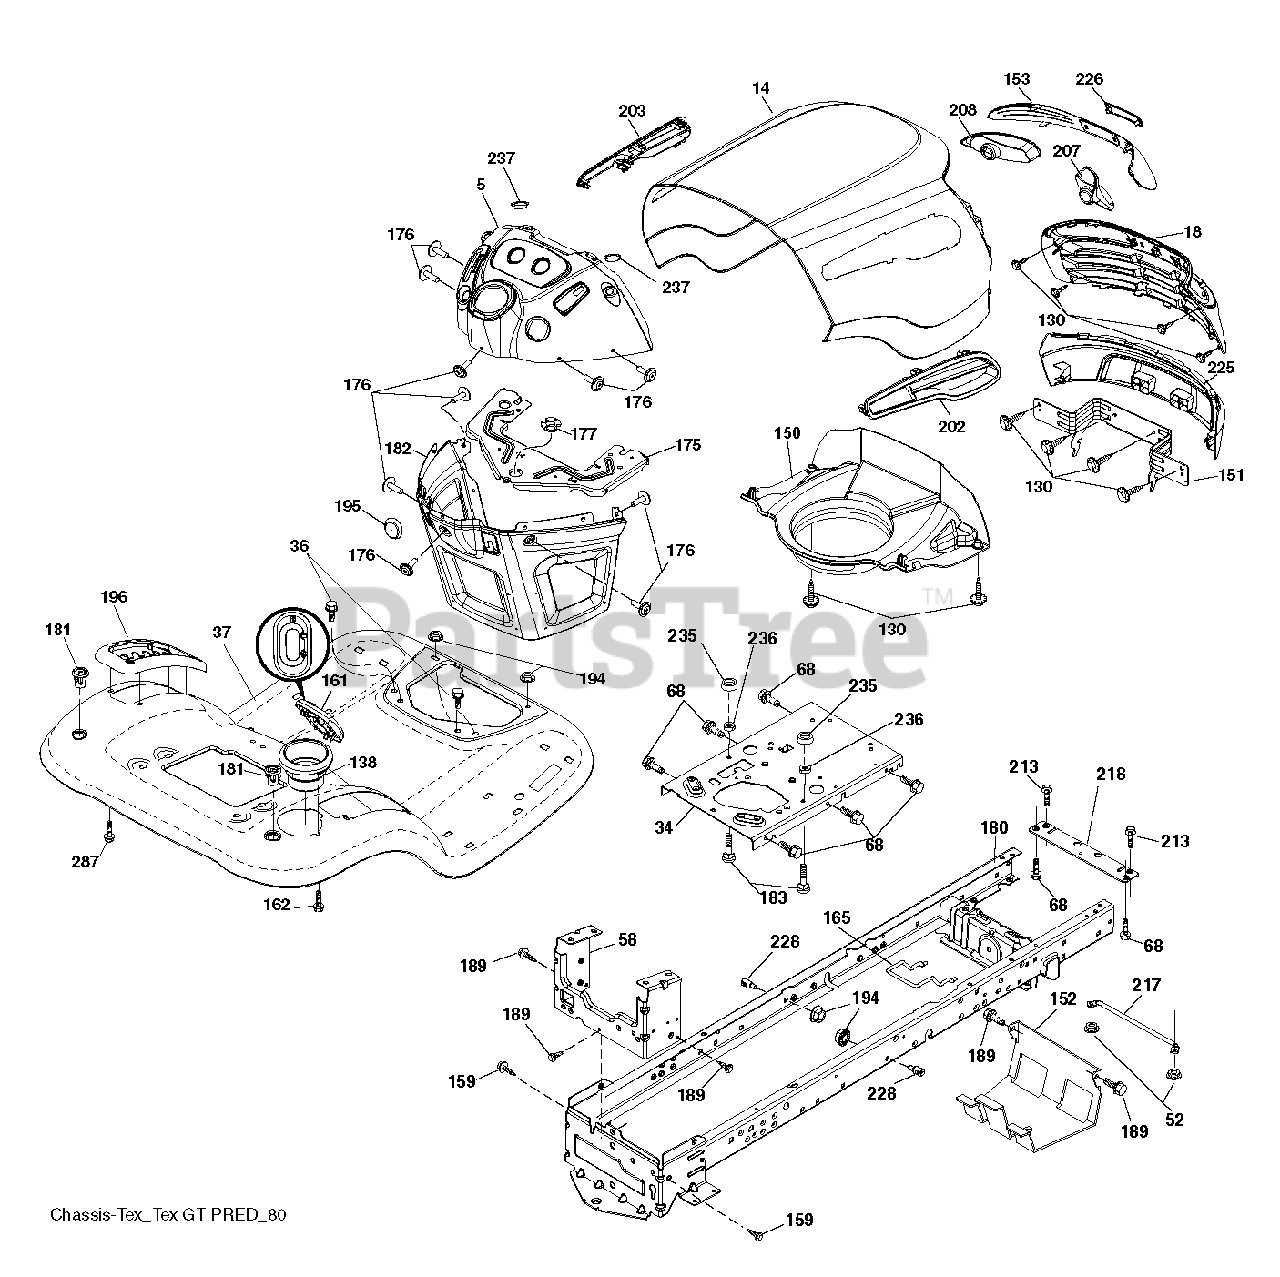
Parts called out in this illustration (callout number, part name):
5	DASH.YT.PRED.RD.GA.ELE.2CY.BLK
14	HOOD.PNT.PREDATOR.YT/GT.BLACK
18	GRILLE.SVC.PREDATOR.YT.TEX
34	PLATE.ENGINE.WELDED.CHASSIS
36	SCREW 5/16"
37	FENDER.TLT.W/CPH.W/FW.BLACK
52	LOCKNUT
58	DRAWBAR UPPER 2PC SMALL FENDER
68	SCREW LT
130	SCREW.#10 X 0.750.BOS (2 2)
138	CUPHOLDER.TL.TEX.BLACK
150	PREDATOR.YT.GT.HOOD.AIR DUCT
151	BRACKET.PIVOT.PREDATOR
152	SHIELD.BROWNING.W/TEX
153	LENS.BAR.PREDATOR.YT.CLEAR
159	SCREW, 3/8-16X3/4
161	WINDOW.FUEL.LT.TEX.BLACK
162	SCREW.HI-LO.CONSOLE
165	SUPPORT.TANK.REAR.W/TEX
175	PLATE.CROSSMEMBER.HUSQ
176	SCREW.#10-24X5/8.RN.QU
177	BUSHING STEERING
180	CHASS.WLDMNT.TL.12GA/2P.48/54
181	FEND/FTRST.PCH.CPH.NFW
182	DASH.LOWER.COMMON.12V.ADAPTOR
183	BOLT.5/16-18X1-1/4 FULL THD
189	SCREW
194	NUT LOCK HEX FLANGE 5/16-18
195	PLUG.HOLE.DASH.
196	DCKLFT.CONSL.10POS.TLT.B/Y
202	VENT.SIDE.HOOD.RH.PREDATOR.BLK
203	VENT.SIDE.HOOD.LH.PREDATOR.BLK
213	BOLT
217	ROD.PIVOT.HOOD
218	X-PIECE.HOOD.STOP.NON/
228	STUD.FASTNER.W/ANTI-ROTATE
235	SPACER FENDER
236	NUT.CENTERLOCK.5/16-
237	PLUG.MOUNT.CARGO.BLK
287	SCREW 1/4X20
